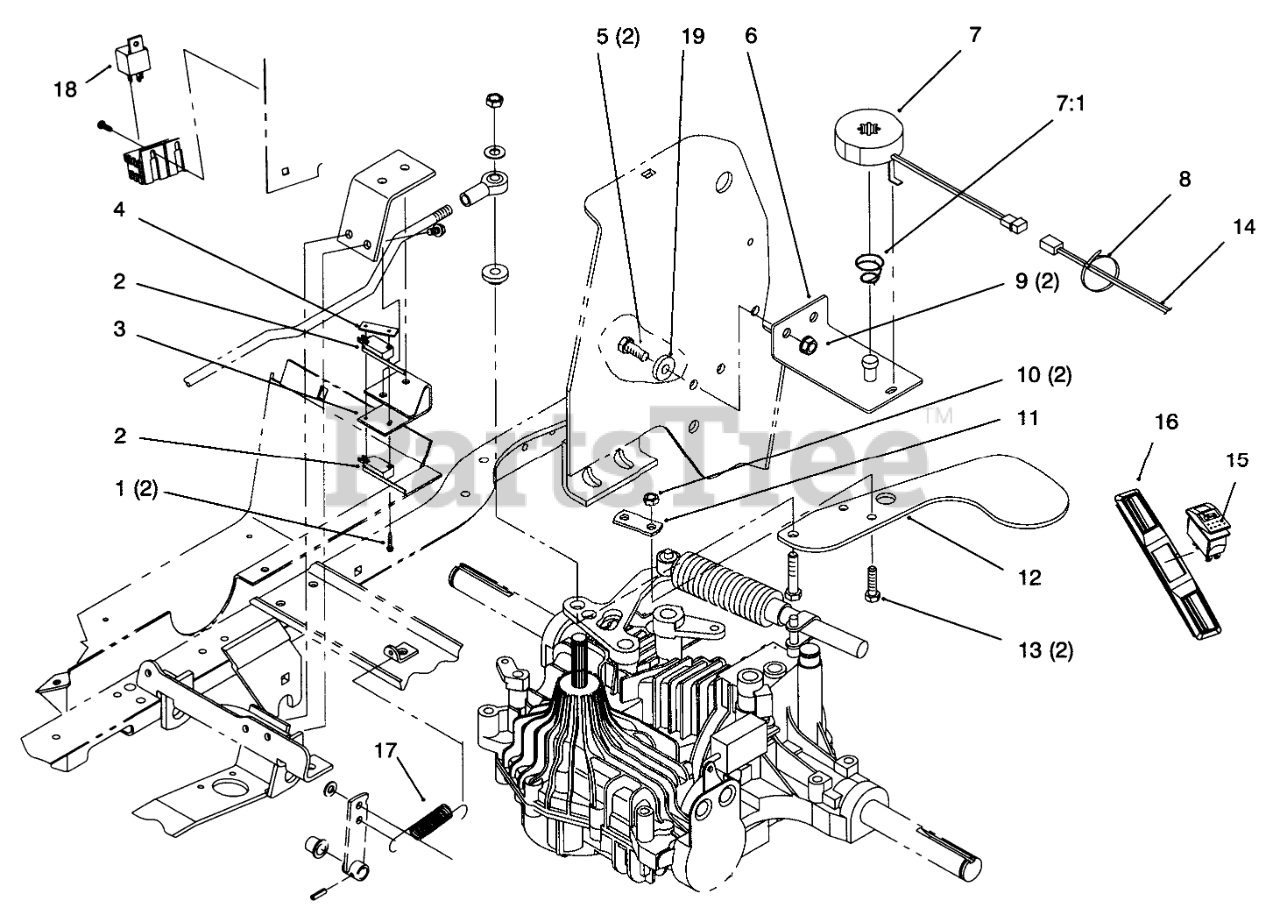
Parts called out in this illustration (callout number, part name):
1	SCREW-HH
2	SWITCH-MICRO
3	Bracket-Switch
4	NUT-SPEED
5	SCREW-HH
6	Cruise Bracket
7	ASM - MAGNET
7:1	SPRING-COMPRESSION
8	TIE-CABLE
9	NUT-LOCK, NI
10	NUT-LOCK, NI
11	CLAMP - CRUISE
12	ARM - CRUISE
13	SCREW-HH
14	HARNESS - WIRE
15	SWITCH-CRUISE
16	COVER-SLOT, RH
17	SPRING-EXTENSION
18	RELAY
19	WASHER-FLAT
